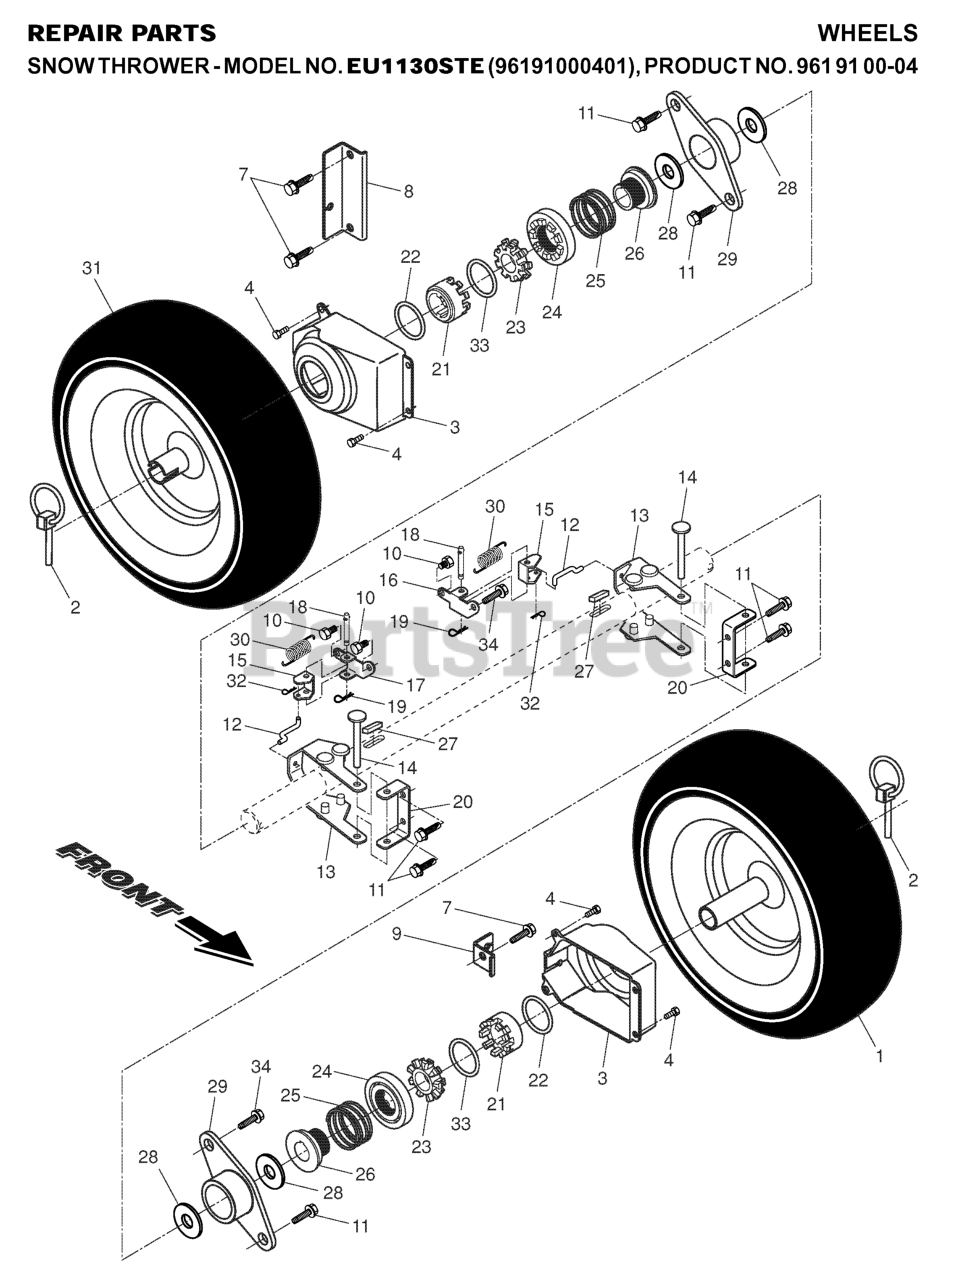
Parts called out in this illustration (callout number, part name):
1	16 X 4.8 LH WHEEL GREY
2	PIN KLIK, 1/4
3	COVER, POWER STEERING
4	SCREW, HEX HEAD, TAPPING
7	SCREW 3/8-16X1
8	BRACKET, STEERING CABLE RH
9	BRACKET, STEERING CABLE LH
10	SCREW 1/4X20
11	SCREW, HEX HEAD 5/16-18 X 1/2
12	LINK, STEERING LEVER
13	YOKE, STEERING
14	PIN, STEERING LEVER
15	BELLCRANK.STEER
16	BRACKET.STEER.PIVOT.LH.YZ
17	BRKT.STEER.PIVOT.RH
18	PIN, STEERING BELLCRANK
19	RETAINER CLIP PM
20	BRACKET.STEER.PNT.BLACK
21	RP.DRIVER WHEEL
22	RING, WIRE RETAINER
23	LOBE WHEEL
24	RP.SLIDE.CLUTCH
25	SPRING, CLUTCH SLIDE
26	RP.LOBE.AXLE
27	KEY, SQUARE 1/4 X .875
28	WASHER TRUST 1"
29	BEARING, AXLE
30	SPRING LATCH
31	16 X 4.8 RH WHEEL
32	RETAINER CLIP
